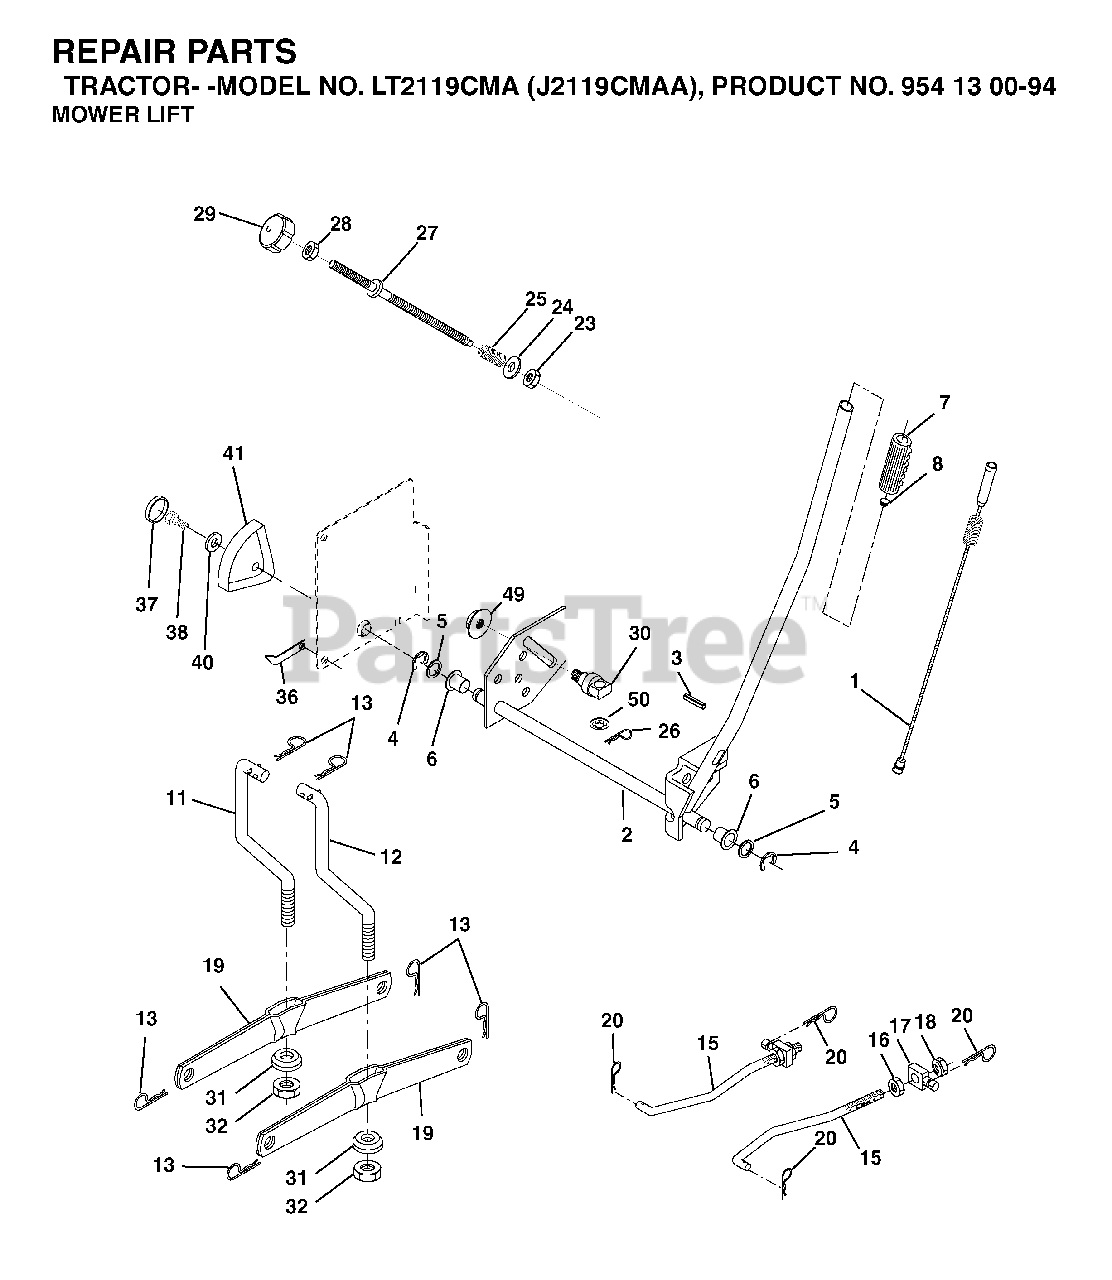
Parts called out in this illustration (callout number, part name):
1	WIRE, INNER
3	PIN GROOVE
4	RETAINING RING LT
6	BEARING.NYLON
7	GRIP HANDLE
8	PLUNGER BUT KIT
11	LINK
12	LINK
13	RETAINER-SPRNG RB
15	LINK.SUSPENSION.FRONT
16	NUT
18	NUT
19	ARM.REAR.SUSPENSION
20	SPRING RETAINER
26	RETAINER CLIP
28	NUT
29	KNOB INF 3/8-16
31	BEARING.PIVOT.LIFT
32	NUT CROWNLOCK 3/8-24
36	POINTER, HEIGHT INDICATOR
37	PLUG,HOLE
38	SCREW 5/16-18X1
41	HEIGHT INDICATOR
49	NUT
50	NUT PUSH M
